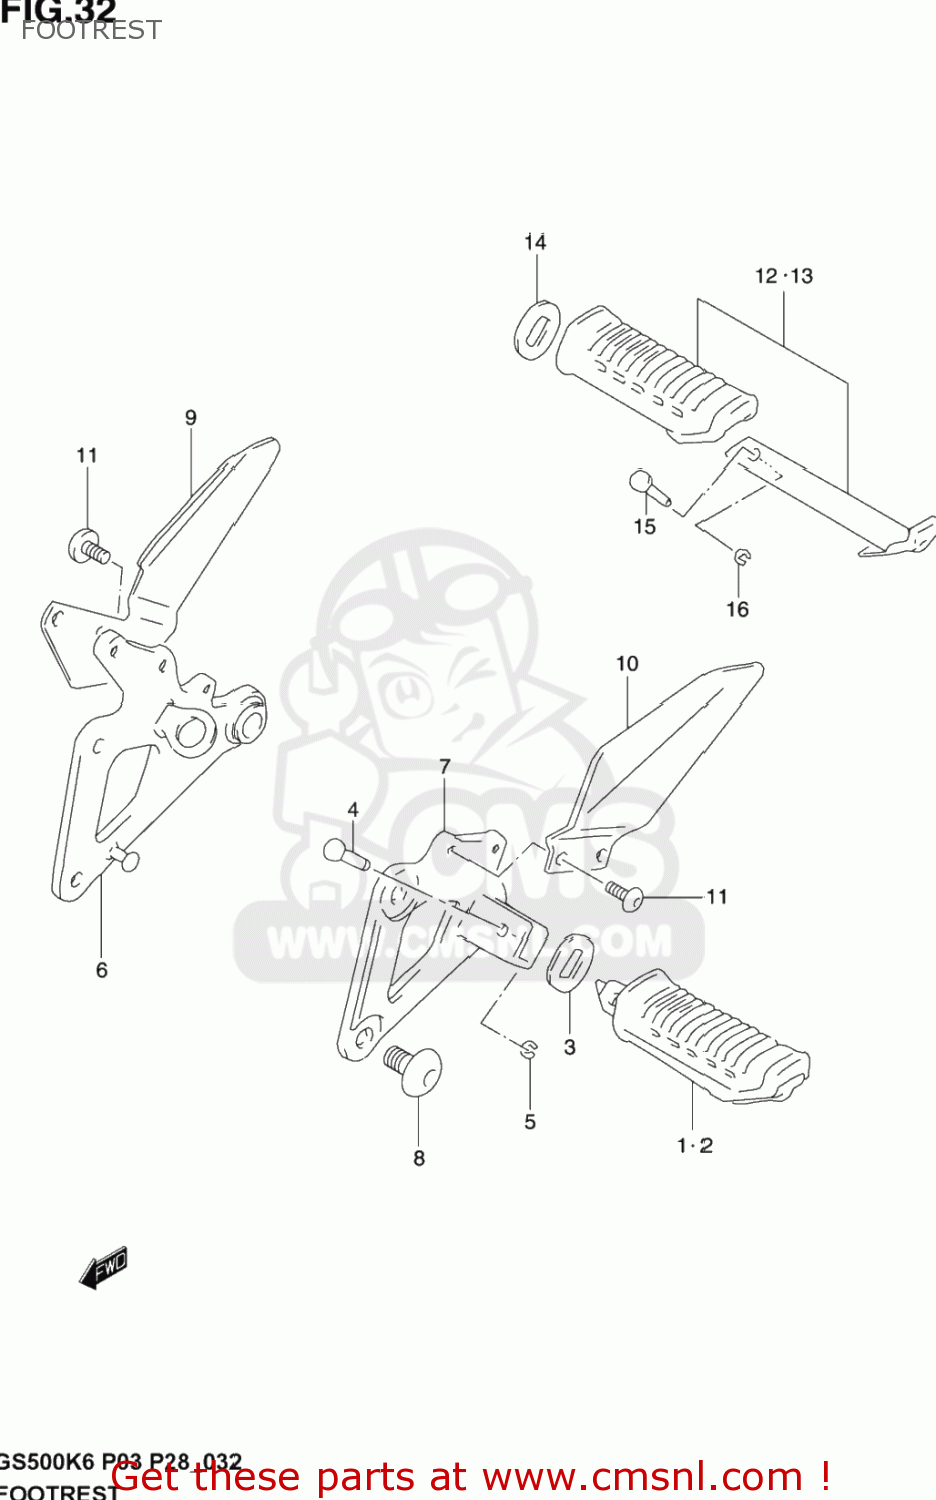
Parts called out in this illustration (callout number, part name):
1	RUBBER ASSY, FRONT RH
2	RUBBER ASSY, FRONT LH
3	WASHER,FOOTREST RUBBER
4	PIN
5	E-RING
6	BRACKET,FR FOOTREST,R
7	BRACKET,FR FOOTREST,L
8	BOLT(8X20)
9	GUARD,FR FOOTREST,R
10	GUARD,FR FOOTREST,L
11	SCREW(6X12)
12	FOOTREST ASSY,PILLION,R
13	FOOTREST ASSY,PILLION,L
14	WASHER,FOOTREST RUBBER
15	PIN
16	E-RING
